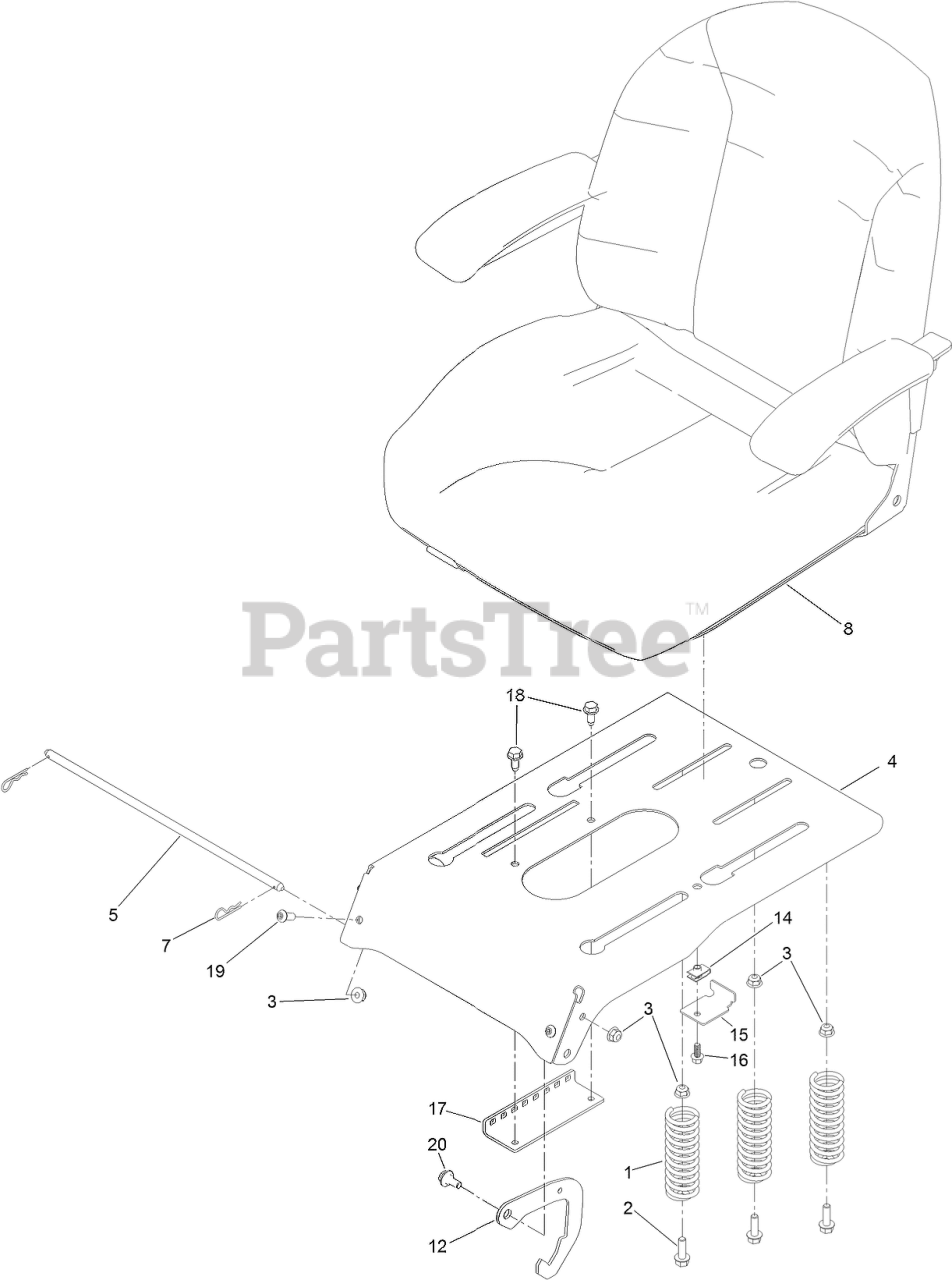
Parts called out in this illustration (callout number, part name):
1	SPRING-COMPRESSION
2	SCREW-HHF
3	NUT-HF, NI
4	PAN-SEAT, DELUXE
5	ROD-PIVOT, NARROW
7	PIN-COTTER
8	SEAT ASM
12	LATCH-SEAT
15	BRACKET-STOP, SEAT
16	SCREW-HHF
17	BRACKET-LATCH, SEAT
18	SCREW-HWHTF
19	SCREW-HSBH
20	SCREW-SHOULDER
